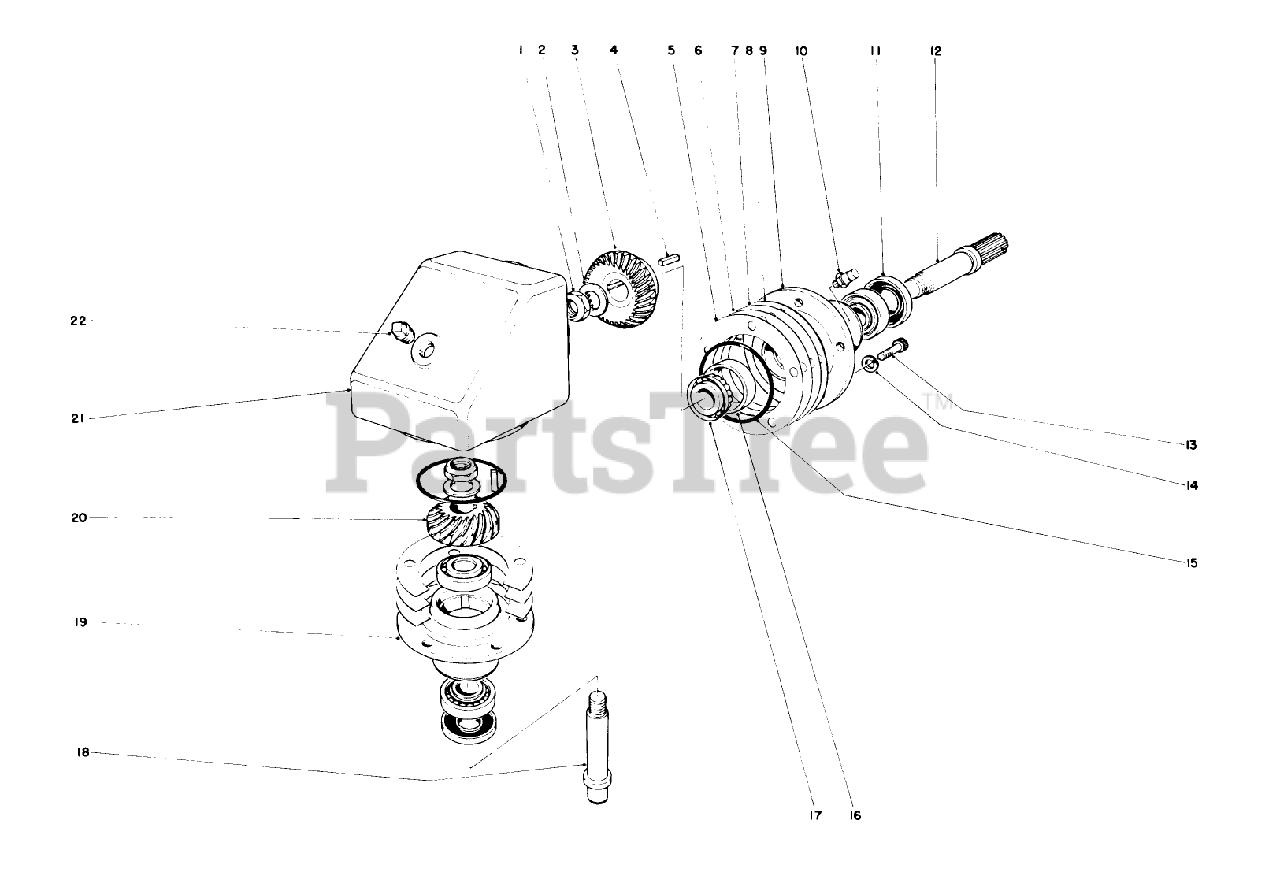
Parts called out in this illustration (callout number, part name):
1	PIN-LYNCH
2	52-INCH CARRIER FRAME ASM
3	PIN-HAIR
4	SCREW-HH
5	PIN-CLEVIS
6	FITTING-GREASE, 90 DEG
8	DECAL-HOC, LH
10	SPACER
11	CUSHION-RUBBER
14	SCREW-HH
15	HUB-CENTER
16	WASHER-FLAT
17	BEARING-OUTSIDE
18	FITTING-GREASE
19	TUBE-INNER (W/VALVE)
20	FEMALE WHEEL HALF
21	MALE WHEEL HALF
22	BEARING-ROLLER
23	SPANNER-TIRE
24	NUT-HEX
25	SCREW-HH
26	NUT-HEX
27	WASHER-THRUST
29	FITTING-GREASE
30	NUT-LOCK, NI
31	SHIM-CUSHION
34	NUT-FLANGE
35	SCREW-HHF, WHIZ
